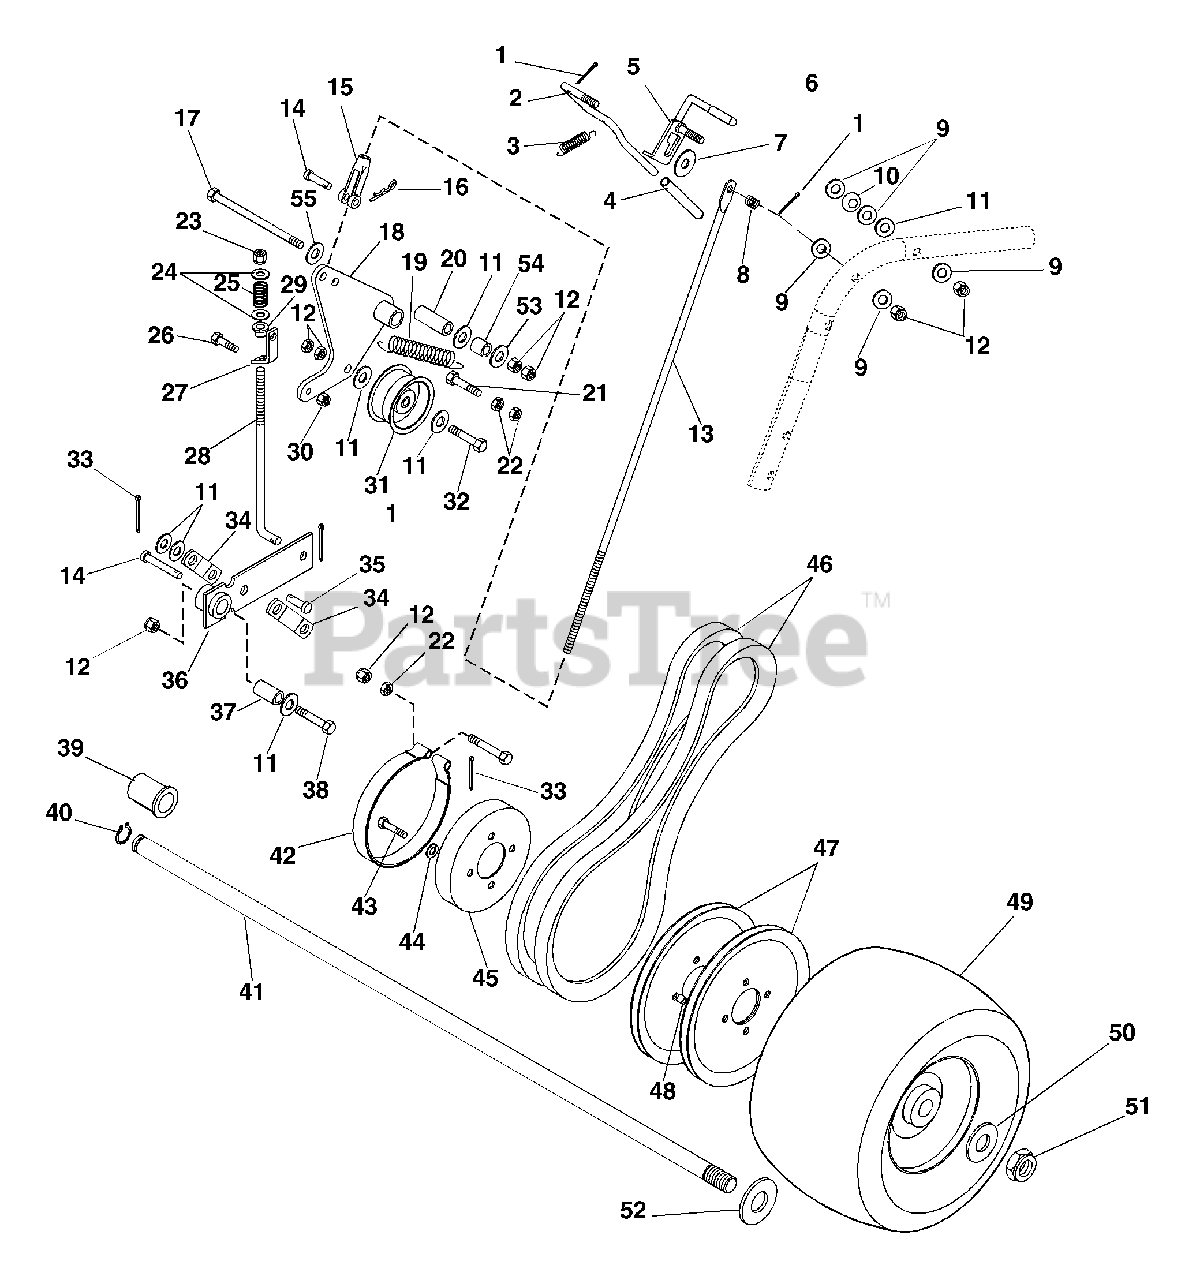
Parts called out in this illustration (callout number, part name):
1	@PIN-CTR .09X.75 EXTPRSQCT YWZ
2	LEVER, HAND CONTROL LH
3	SG-TENS .041X.500X1.750
4	GRIP,HAND CLUTCH LEVER
5	WLDMT,CLUTCH-BRAKE LOCK
6	TIP - BRAKE LOCK LEVER
7	WSHR-FL-STL .406X1.375X.135 YZ
8	SG-COMP .045X.600X.750 WLD7.5
9	WSHR-FL-NY .375X.75X.060
10	SPRING WASHER
11	@WSHR-FL-STL.406X.812X.065 YWZ
12	@NUT-LK-CTR .38-16 YWZC
13	ROD,CLUTCH ACTUATING
14	PIN-CLEV .38X1.25 YWZC
15	CLEVIS, .38-24 ADJ.
16	PIN-HAIR INT .08X.18X1.18 YWZC
17	@BLT-HEX .38-16X4.00 GR5 YWZC
18	WLDMT,WHL CLUTCH ARM
19	SG-TENS .069X.62X3.50 WLD20
20	BUSH.,S.385X.610X1.80 ST
21	@BLT-HEX .38-16X1.50 GR5 YWZC
22	@NUT-LK-CTR .38-16 YWZC
23	@NUT-LK-CTR .31-18 YWZC
24	@WSHR-FL-STL.344X.688X.065YWZC
25	SG-COMP .125X.78X1.00 YWZ
26	@BLT-HEX .25-20X.75 GR5 YWZC
27	L-BKT, PRO BRAKE LINK
28	ROD,BRAKE
29	BSHG-FLG .320X.620X.312 NY
30	@NUT-LK-CTR .25-20 YWZC
31	IDLER 2.75X1.25
32	@BLT-HEX .31-18X2.25 GR5 YWZC
33	@PIN-CTR .12X.75 EXTPRSQCT YWZ
34	LINK,BRAKE ARM
35	PIN-CLEV .38X.75 YWZC
36	WLDMT,BRAKE ARM
37	BUSH.,S.391X.622X.950 ST
38	@BLT-HEX .38-16X2.00 GR5 YWZC
39	BSHG-FLG 1.010X1.38X1.4X1.65
40	RG-RTNG-EXT 1.00X.078
41	AXLE SHAFT, PRO-150
42	ASM, BRAKE BAND, PRO
43	@BLT-HEX .31-18X1.50 GR5 YWZC
44	@WSHR-LK .31X.078 REG YWZC
45	DRUM,BRAKE
46	V-BELT, HA-COGGED (SET)
47	PLY-V 9.00X3.75
48	BUSH.,S.385X.625X.475 ST
49	TIRE/WHEEL ASSY, 13X6.50-6
50	WSHR-FL-STL 1.010X1.505X.062YZ
51	@NUT-LK-CTR .44-14 YWZC
52	WSHR-THRST 1.55X1.002X.093
53	WSHR-FL-STL .328X.87X.179 YWZC
54	BSHG-SLV .391X.688X.52 PM
55	WSHR-FL-STL.44X1.625X.315 YWZC
